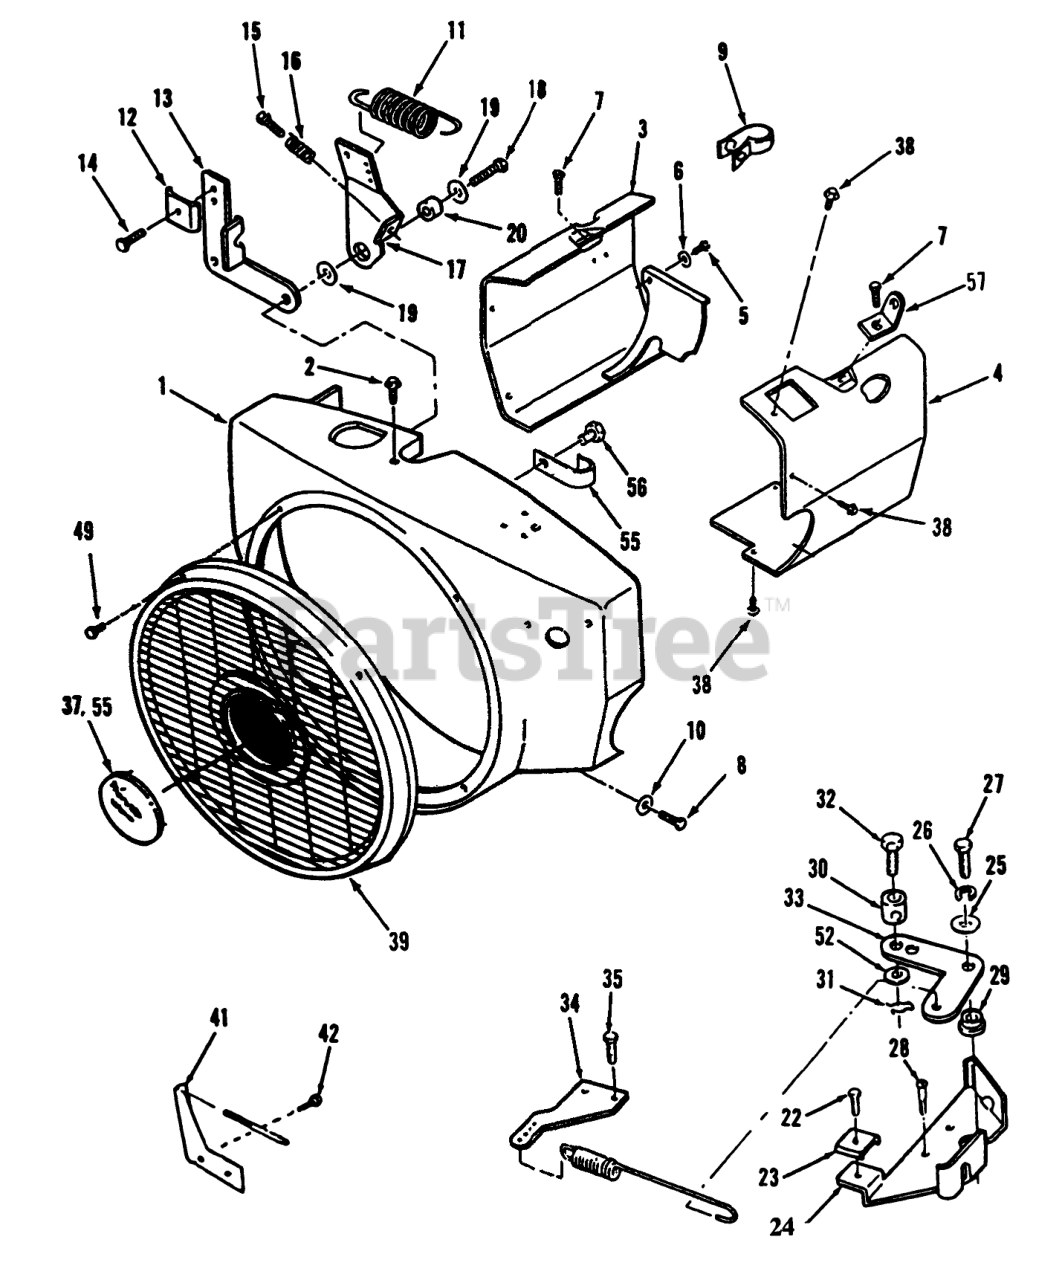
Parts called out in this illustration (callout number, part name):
1	BLOWER-HOUSING
2	HEX HD CAPSCREW
3	CYLINDER AIR HSG L H
4	Housing, Cylinder Air-RH
5	SCREW-HH
6	WASHER-FLAT
7	SCREW-HWH
8	SCREW-HH
9	Clamp
10	WASHER-FLAT
11	SPRING
13	Bracket
14	SCREW-TAPPING
15	SCREW-TAP
16	SPRING
17	Arm, Governor Control Without Swivel-Zinc Plated
19	WASHER-FLAT
20	BUSHING
22	SCREW-HWH
24	BRKT-GOVERNOR CONTRL
25	WASHER-FLAT
26	Washer-Lock
27	Bolt
28	HEX HD CAP SCREW
29	BUSHING-GOV CONTROL
30	BUSHING
31	PIN-COTTER
32	Bolt
33	LINK-GOV CONTROL
34	ADAPTER-GOV ARM
35	SCREW-TAPPING PAN HD
37	Plug
38	SCREW-HWH
39	GUARD-STATIONARY
41	BRACKET
42	SCREW-HWH
48	SCREW - THREAD CUTTING
49	SCREW-PAN HEAD
55	CLIP-WIRE
56	SCREW-HWH
57	BRACKET-LIFTING
